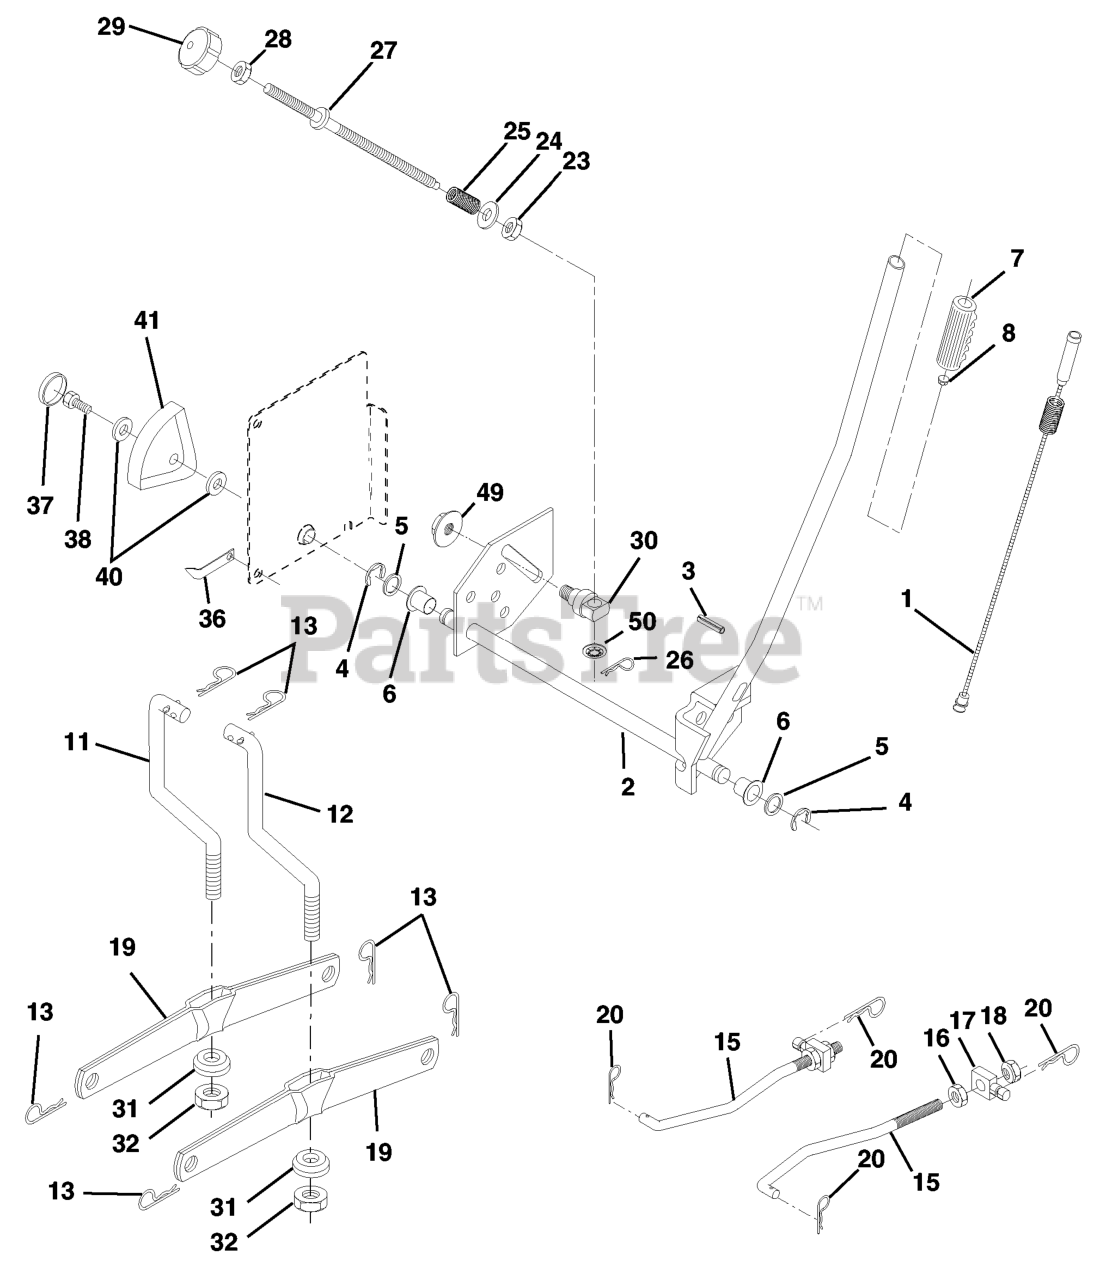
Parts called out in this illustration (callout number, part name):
1	WIRE ASM INNER W/ PLUNGER LT
2	SHAFT ASM R HANDLE
3	PIN GROOVE.
4	RETAINING RING LT
6	BEARING.NYLON
7	GRIP HANDLE
8	PLUNGER BUT KIT
11	LINK
12	LINK
13	RETAINER-SPRNG RB
15	LINK.SUSPENSION.FRONT
16	NUT.HEX.JAM.1/2-13
17	TRUNION
18	NUT.LK.W/WSH.1/2.
19	ARM.REAR.SUSPENSION
20	SPRING RETAINER
25	SPRING**
26	RETAINER CLIP
27	ROD ADJ LIFT
28	NUT
29	KNOB INF 3/8-16
31	BEARING PIVOT
32	NUT CROWNLOCK 3/8-24
36	POINTER, HEIGHT INDICATOR(2 2)
38	SCREW 5/16-18X1
41	HEIGHT INDICATOR
49	NUT
50	NUT PUSH M
